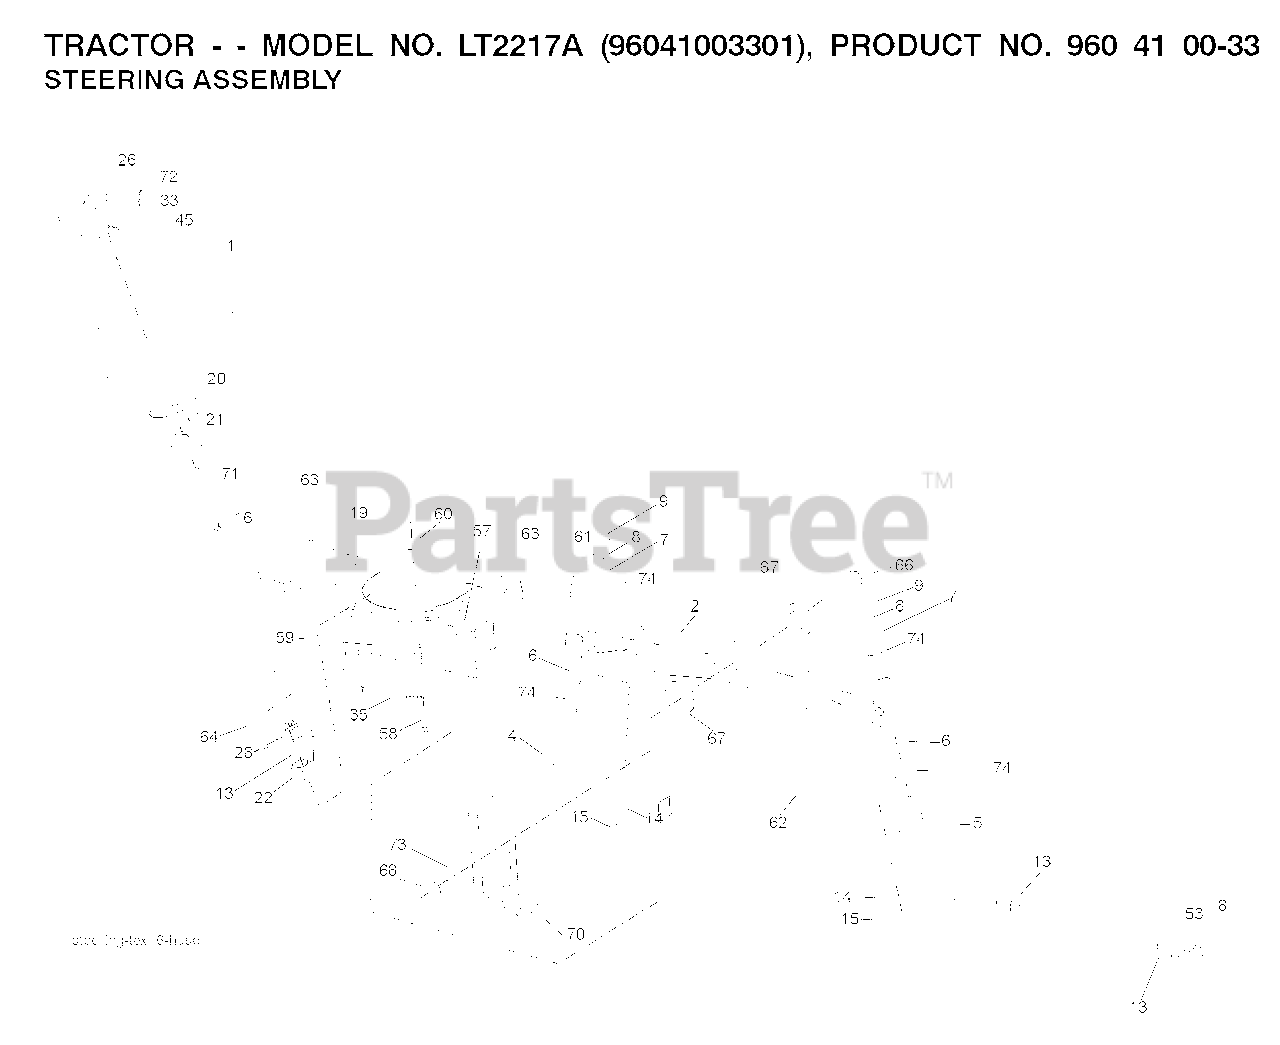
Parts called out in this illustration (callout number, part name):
1	WHEEL.STEERING.PREM.2.BLK
2	AXLE.HALF.ASM.WELDED
4	SPINDLE.WELDED.LH.15"TEX
5	SPINDLE.WELDED.RH.15"T
8	RING CLIP
9	CAP.SPINDLE
14	WASHER, LOCK 3/8
15	NUT CROWNLOCK 3/8-24
16	SHAFT STEERING
19	PLATE.STEER.DDL.NLT/NG
20	BOOT STEERING BLACK
21	ADAPTER, WHEEL STNG..
22	BUSHING.ASM.STEERING.A
26	INSERT.CAP.STRG.WH.BLACK
28	SCREW, 3/8-16X3/4
33	LOCKWASHER
35	GEAR.SECTOR.PLATE.DDL.
45	WASHER.11/32
53	WASHER.HARDENED
57	BRACKET.UPSTOP.TEX
58	BOLT.SHOULDER.SECTOR.P
59	WASHER.THURST.SECTOR.S
60	NUT FLANGE LOCK 5/8-11
61	DRAGLINK.LH.BALLSTUD.D
62	DRAGLINK.RH.BALLSTUD.D
63	SCREW
64	RETAINER.CLIP.SPRING.S
66	BOLT HEX FGHD 7/16-14 X 3 SERR
67	BUSHING.PM.FRONT AXLE
68	NUT.LOCK.FLANGE.7/16
70	BRKT.DECK.SUSPENSION.F
71	SHAFT EXTENSION STEERING
72	BOLT YT
73	WASHER.1.5X.505X.118
74	BRNG T
